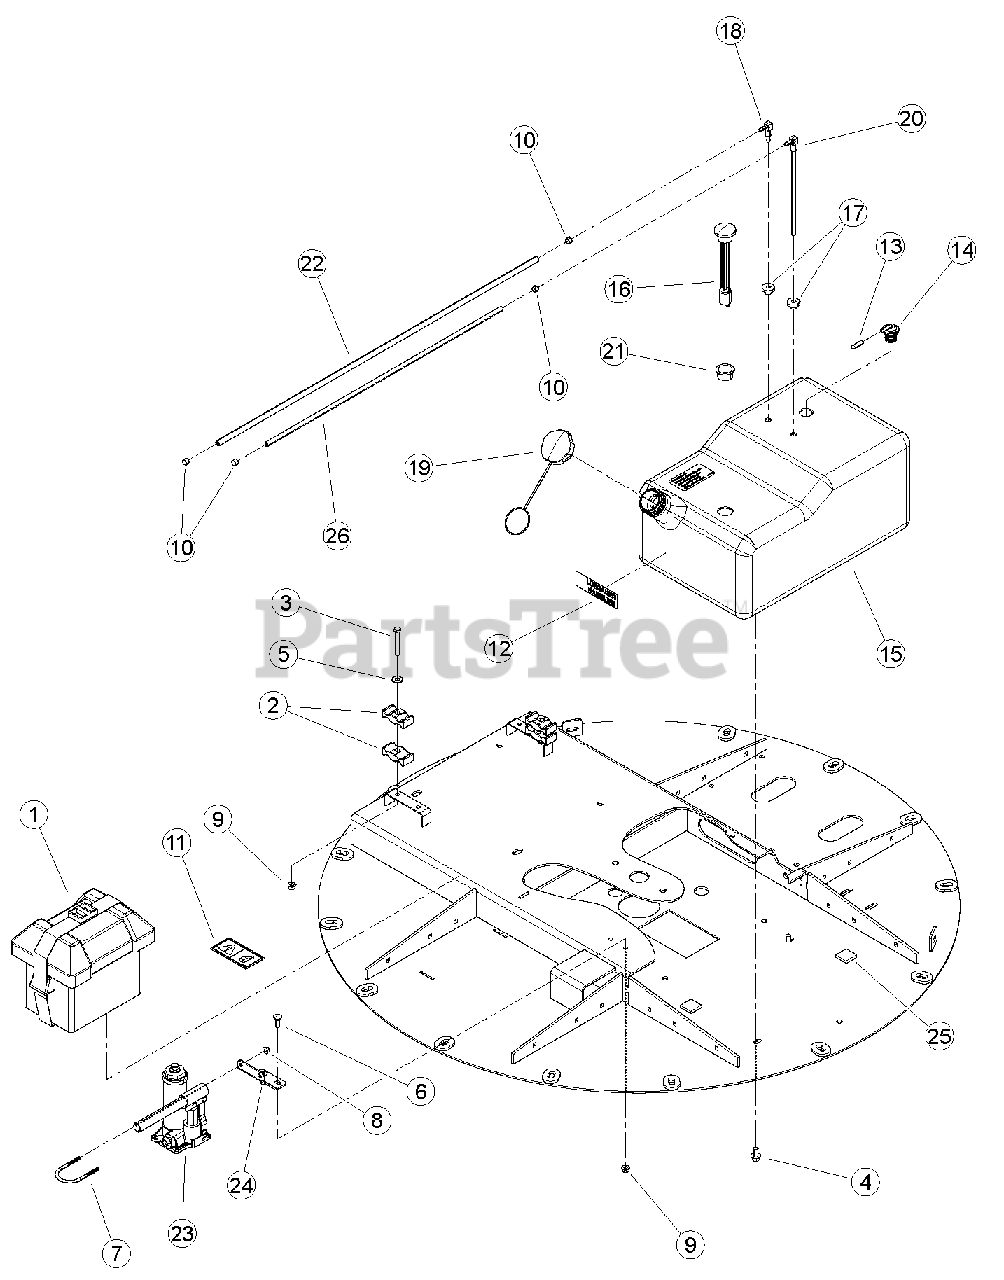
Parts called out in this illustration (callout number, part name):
1	BOX, SMALL BATTERY
2	CLAMP, PLASTIC HOSE
3	BOLT, 5/16 X 2-1/2 G5 HEX CAP ZP
4	BOLT, 3/8 X 3/4 FLANGE NC
5	WASHER, 5/16" FLAT ZP
6	BOLT, 5/16 X 1" GR5 CRG ZP
7	U-BOLT, 1/4 X 1-1/2 PIPE
8	NUT, 1/4-20 NYLOCK-FLANGE
9	NUT, 5/16-18 NYLOCK-FLANGE
10	CLAMP, 15/32 SPRING
11	DECAL, LOCK
12	DECAL, UNLEADED GASOLINE
13	CAP, EPDM BLACK .223 ID X 1.0 LG X .06 WALL
14	VALVE, ROLL OVER
15	TANK, ROTOMOLDED FUEL
16	GAUGE, FUEL LEVEL KELCH 100
17	GROMMET, TANK FITTING
18	FITTING, TANK VENT
19	CAP, FUEL TANK VENTED
20	FITTING, TANK FUEL PICK-UP TUBE
21	GROMMET, KELCH 100 GAUGE
22	HOSE, 38" FUEL LINE
23	JACK, HYDRAULIC 2 TON
24	PLATE, JACK MOUNT
25	PAD, FOAM FUEL TANK DAMPER
26	HOSE, 28 INCH FUEL LINE 1/4"
